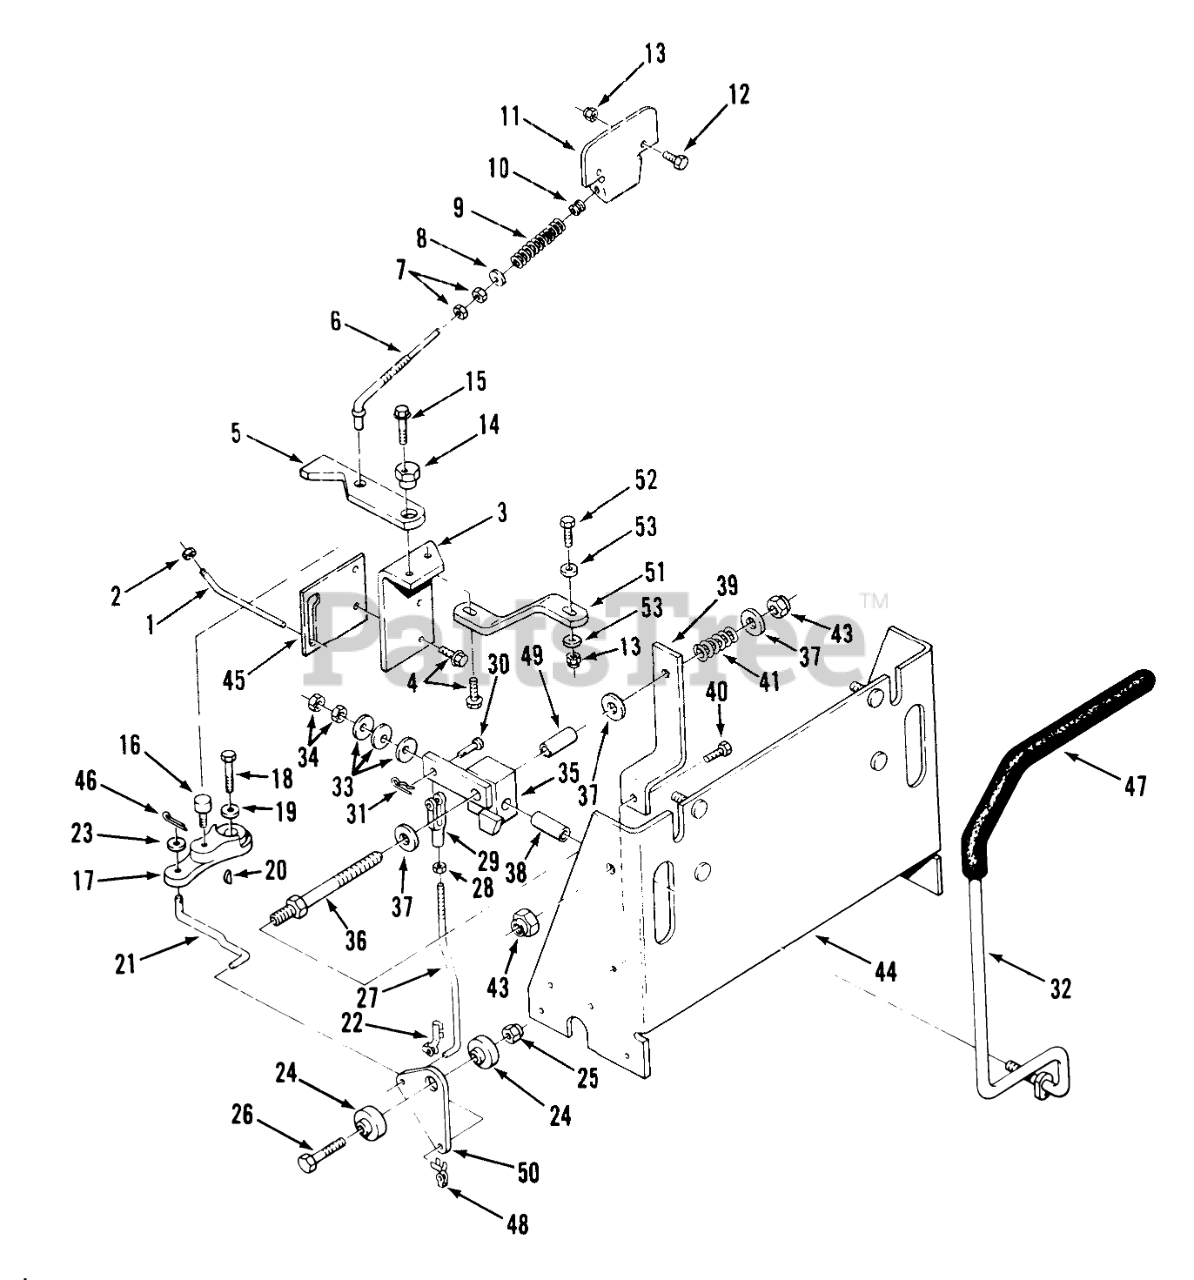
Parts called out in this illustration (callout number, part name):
1	LEVER-TOW VALVE
2	Nut
3	Bracket RH
4	Bolt
5	Arm
6	ROD-NEUTRAL RETURN
7	Nut
8	Washer
9	SPRING COMPRESSION
10	NYLINER BUSHING
11	Bracket
12	Bolt
13	Nut
15	Bolt
16	BEARING-CAM ROLLER
17	ARM-SPEED CONTROL
18	Bolt
19	WASHER
20	KEY WOODR 1/8X1/2 DI
21	LINK-R.H.
22	CLIP-CLEVIS L.H.
24	SPACER-CLUTCH LINK
25	NUT
26	Bolt
27	ROD-HYDRO CTRL. ADJ.
28	Jam Nut 1/4-28
30	Pin
32	R/H STRG LEVER B
33	SPRING-BELLVILLE
34	Jam Nut
35	Lever Pivot RH
36	SHAFT-PIVOT
37	Washer
38	BUSHING-STR LVR PVT
39	Bracket-Retainer
40	Screw
41	SPRING
43	Nut
44	Lever Support
45	PLATE-TOW VALVE L
46	Cotter Pin
47	Grip
48	CLIP-CLEVIS R.H.
49	BUSHING
50	PLATE-CONTROL PIV
52	Bolt
53	WASHER 5/16 SAE
